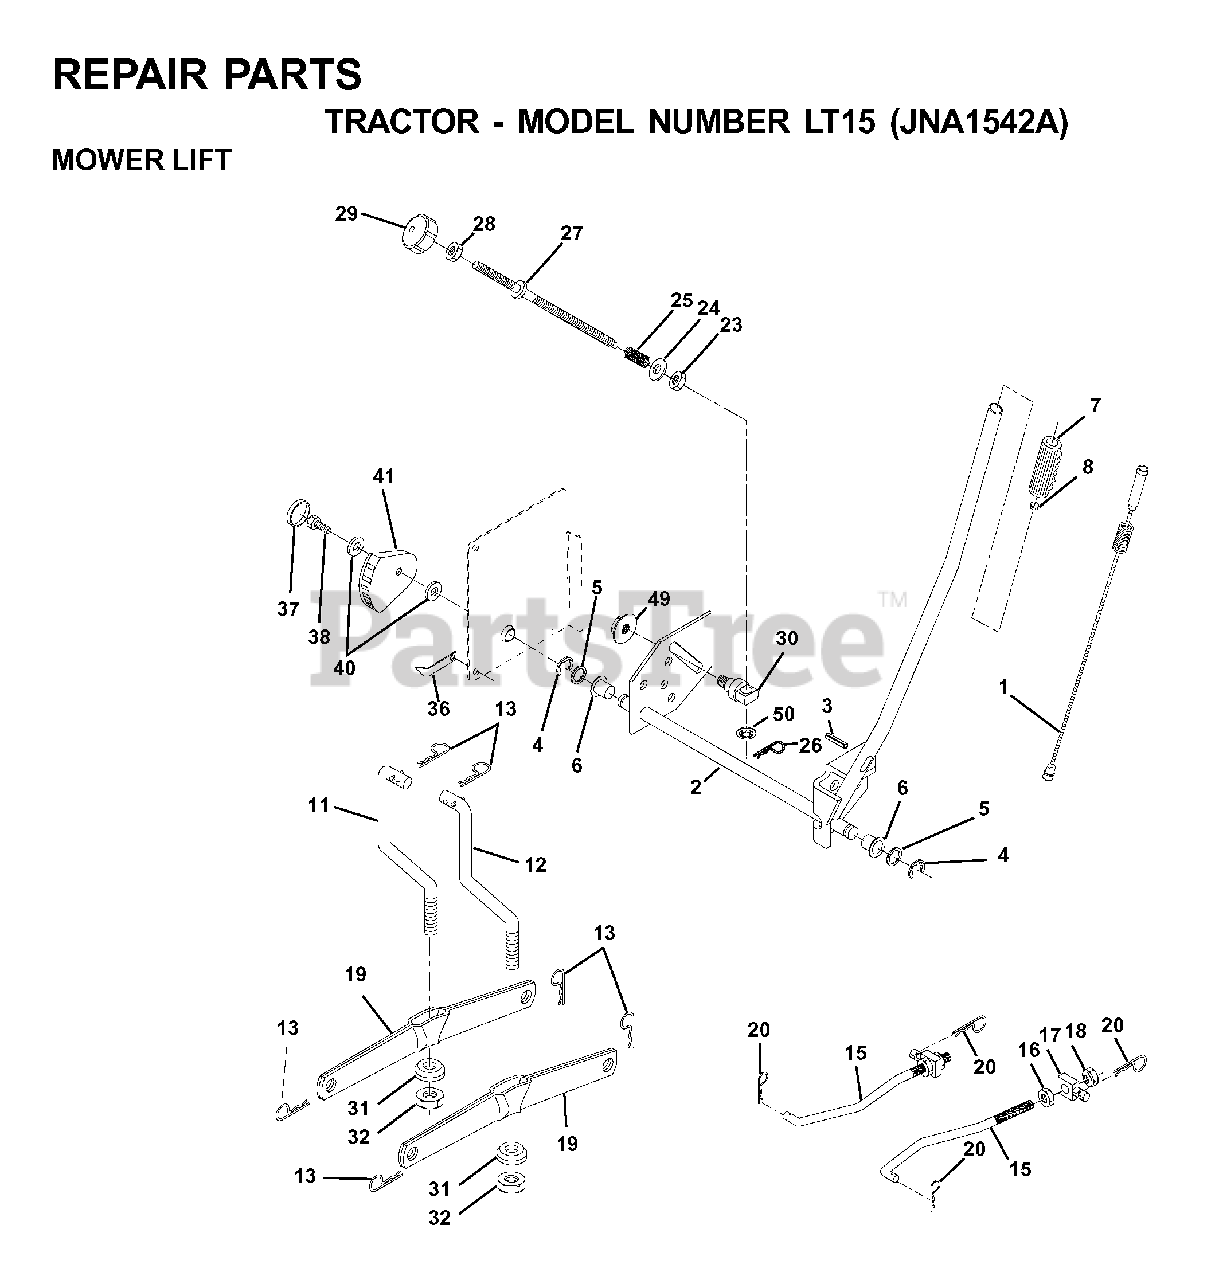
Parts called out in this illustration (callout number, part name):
1	WIRE ASM INNER W/ PLUNGER LT
2	SHAFT ASM R HANDLE
3	PIN GROOVE
4	RETAINING RING LT
6	BEARING.NYLON
7	GRIP HANDLE
8	PLUNGER BUT KIT
11	LINK LIFT LH
12	LINK LIFT RH
13	RETAINER-SPRNG RB
15	LINK.SUSPENSION.FRONT
16	NUT
17	TRUNION
18	NUT
19	ARM.REAR.SUSPENSION
20	SPRING RETAINER
25	SPRING**
26	RETAINER CLIP
27	ROD ADJ LIFT
28	NUT
29	KNOB INF 3/8-16
31	BEARING.PIVOT.LIFT
32	NUT CROWNLOCK 3/8-24
36	POINTER, HEIGHT INDICATOR
37	PLUG,HOLE
38	SCREW 5/16-18X1
41	IND. HEIGHT STLT
49	NUT
50	NUT PUSH M
